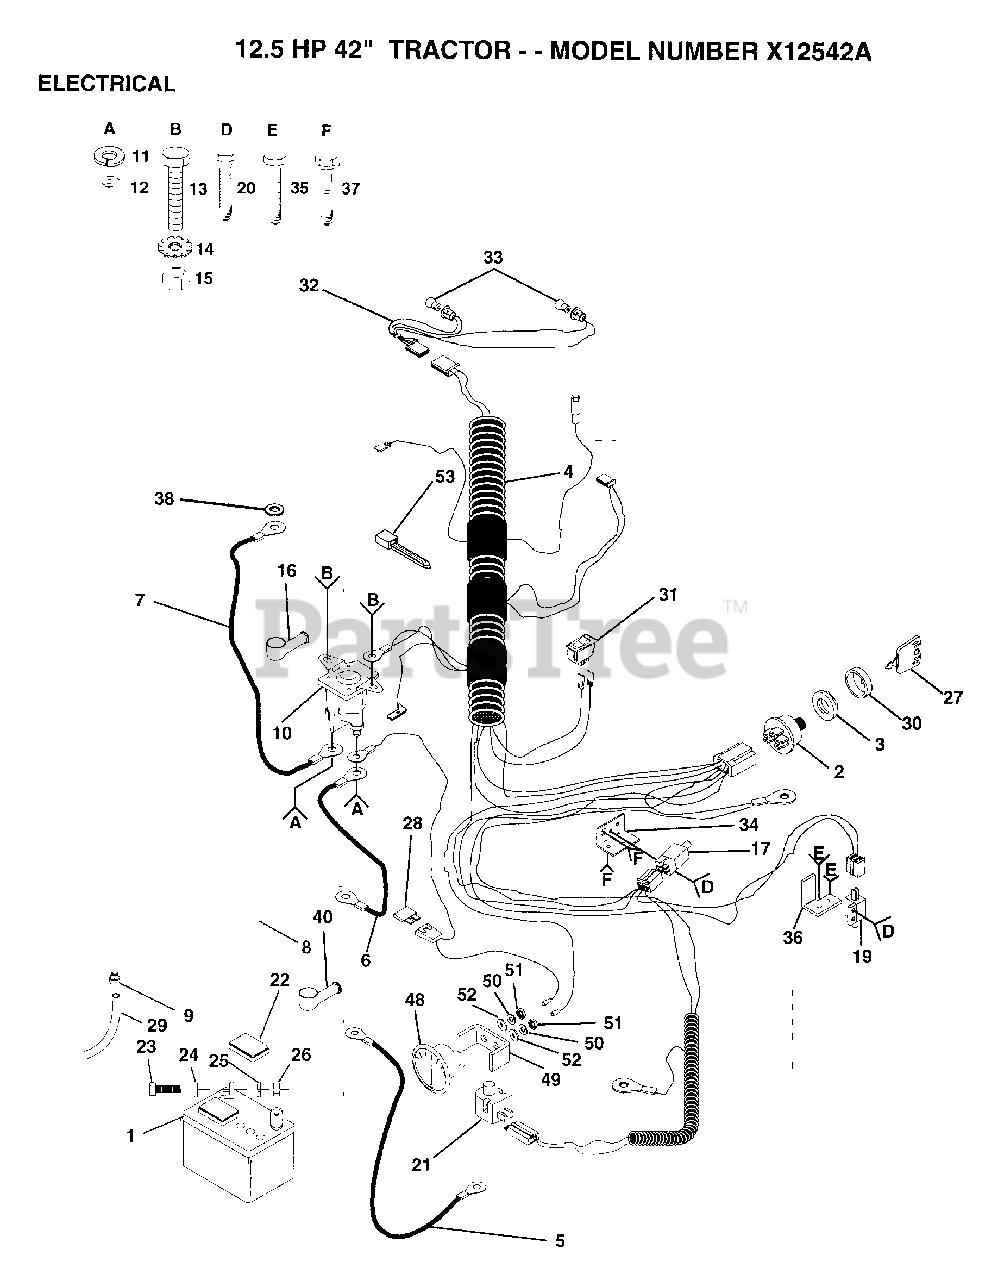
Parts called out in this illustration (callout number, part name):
3	NUT IGNITION
4	HARNESS.IGN
5	CABLE T
7	CABLE-BATTERY T
8	BTRY CASE W/O LID
9	HOSE CLAMP T
12	NUT
13	BOLT
15	NUT
17	SWITCH INTERLOCKT
19	SWITCH-INTER. GT
20	SCREW
21	SWITCH SEAT
22	"CAP,BATTERY "
23	BOLT LT
24	WASHER
25	LOCKWASHER
27	KEY
28	FUSE HYT
29	TUBE T
31	SWITCH LT
34	SWITCH BRACKET
35	SCREW
36	BRACKET LT
37	SCREW
38	LOCKWASHER
48	AMMETER T
52	WASHER
53	WIRE TIE
